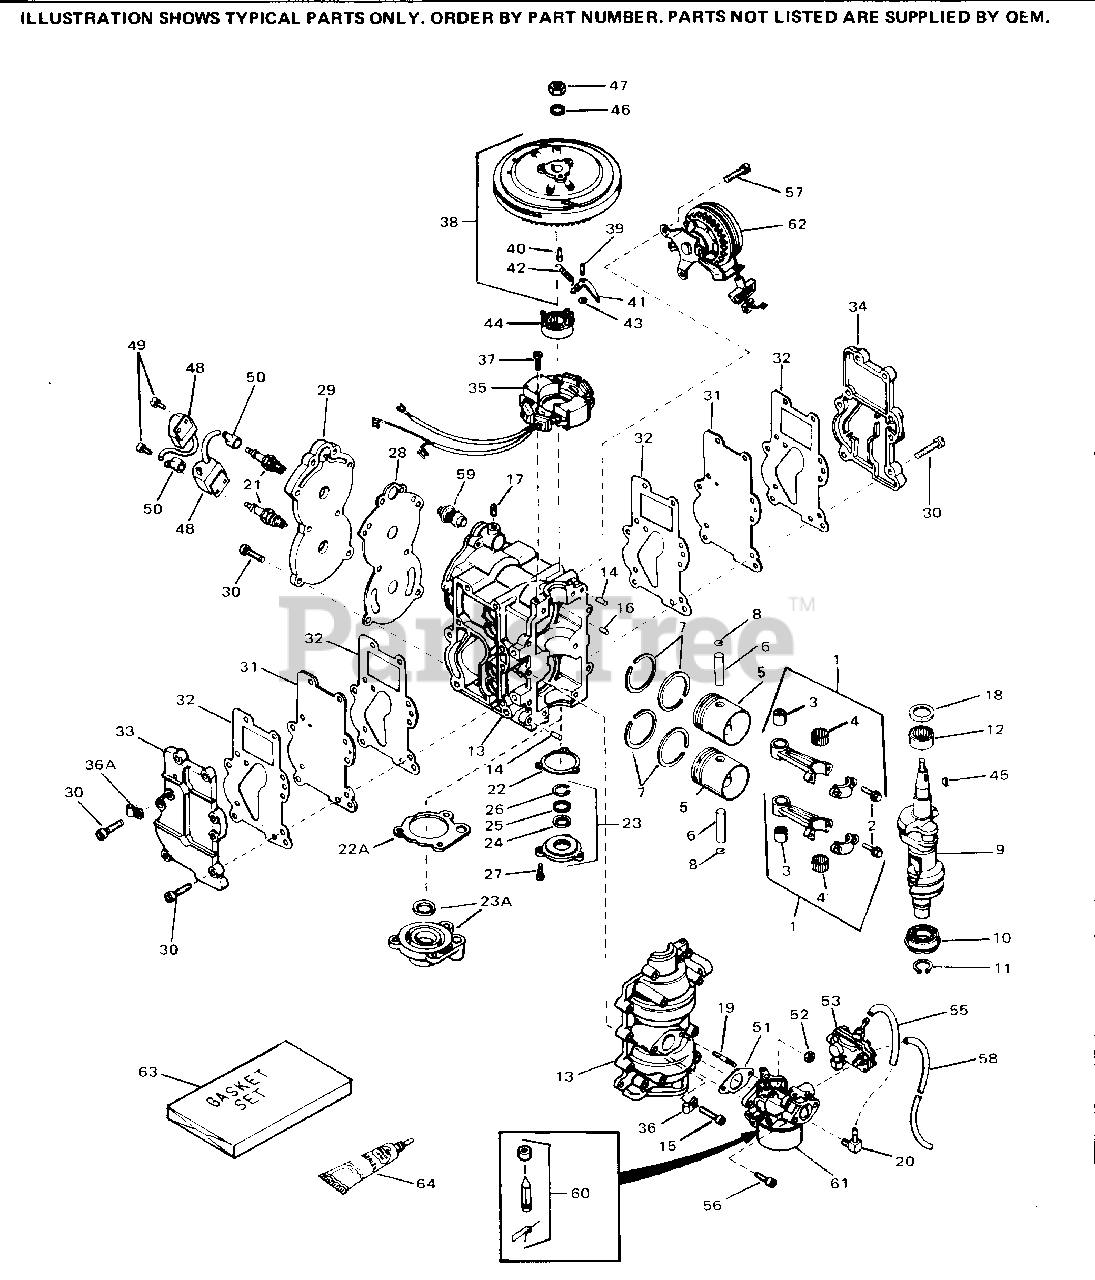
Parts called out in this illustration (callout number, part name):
1	"Rod Assy., Connecting
2	Screw, Connecting rod
3	Bearing, Cartridge
4	Bearing Set, Needle (28 Needles)
5	Piston & Pin Assy.
6	Pin, Piston
7	Ring Set, Piston
8	Ring, Retaining
9	Crankshaft
10	Bearing, Ball
11	Ring, Retaining
12	Bearing, Cartridge
13	Block Assy., Cylinder
14	Pin, Dowel
15	Screw, Pan hd., 1/4-20 x 1/4
16	Pin, Dowel
17	Plug, Pipe (Hex countersunk headless,
18	Seal, Oil
19	Stud, Carburetor
21	Plug, Spark (Champion RJ-12YC or equi valent)
22A	Gasket, Bearing cap
23A	Cap & Seal Assy., Bearing
27	Screw, Pan flex hd., 10-24 x 5/8
28	Gasket, Cylinder cover
29	Cover, Cylinder
30	Screw, Hex washer hd. taptite, 1/4-20 x 1
31	Plate, Water jacket
32	Gasket, Exhaust
33	Cover, Exhaust (R.H.)
34	Cover, Exhaust (L.H.)
35	Magneto, Solid state
36	Clip, Cable
36A	Clip, Cable
37	Screw, Torx pan flex hd., 10-24 x 7/8
38	Flywheel Assy.
39	Pin, Pivot
40	Pin, Anchor
41	Weight, Spark advance
43	Ring, Retaining
44	Advance Assy., Spark
45	Key, Flywheel
46	Washer, Lock
47	Nut, Washer hex faced, 1/2-20
48	Transformer Assy.
49	Screw, Int. torx hd., 10-24 x 1/2
50	Cover, Spark plug
51	Gasket, Carburetor
52	Nut, Flange whiz lock, 1/4-28
57	Screw, Hex hd. flange whizlock, 1/4-2 0 x 1/2
58	Line, Fuel
59	Thermostat
60	Inlet Needle, Seat & Clip Assy.
61	Carburetor
62	Rewind Starter, Side mount
63	Gasket Set
64	Sealer (3 oz. tube)
